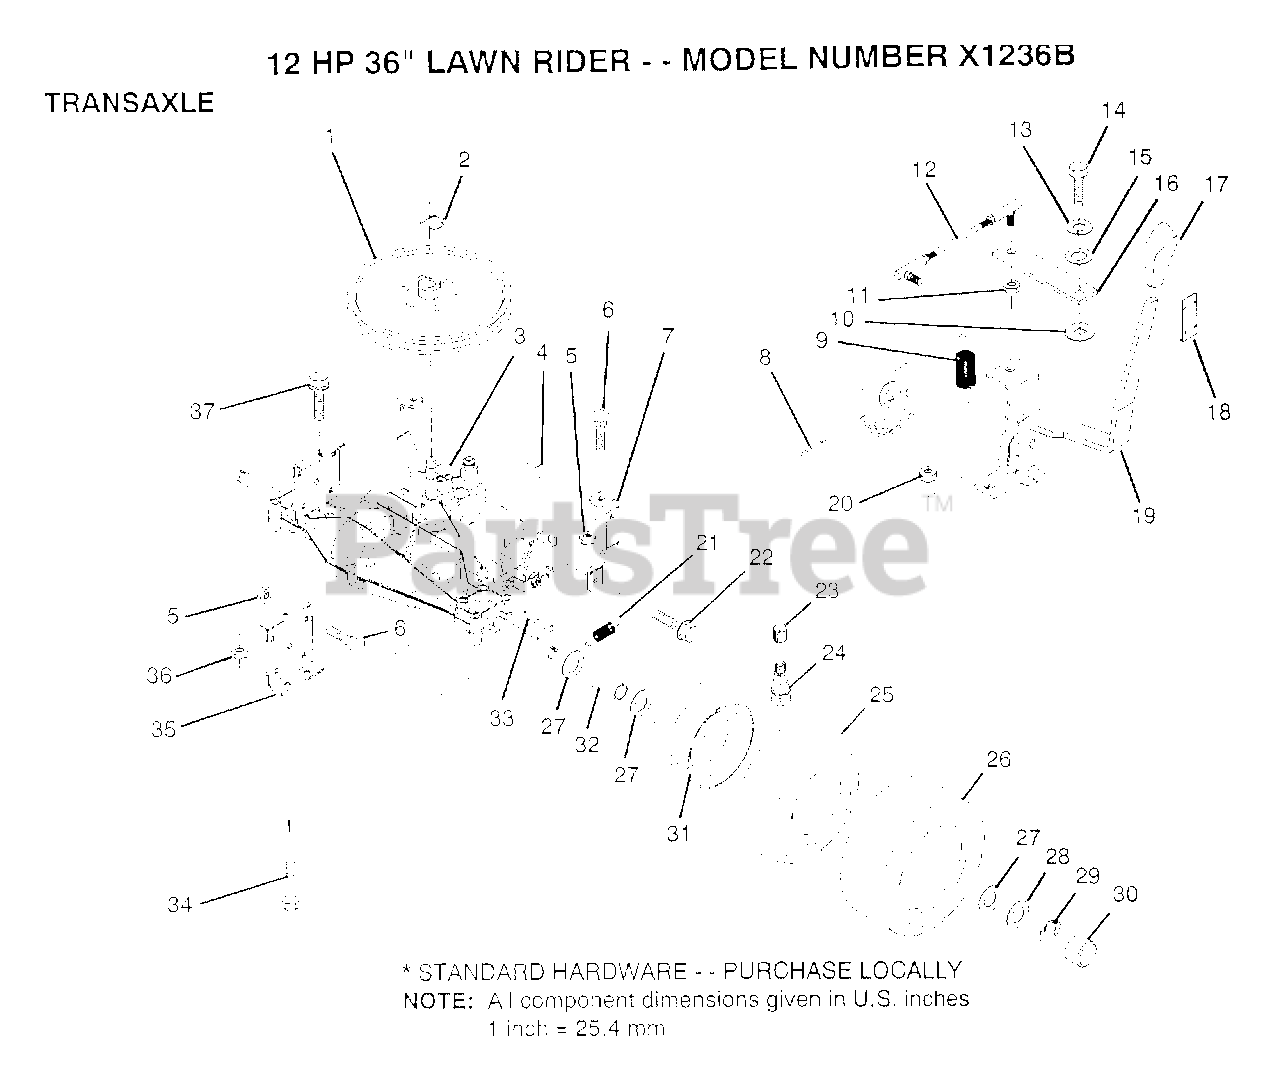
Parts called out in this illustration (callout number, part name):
1	PULLEY
6	BOLT
7	"STRAP,TORQUE"
8	PIN COTTER 1/8
9	"SPRING,EXT"
10	WASH-SHFT PLT LT
11	NUT.LOCK.5/16-24
12	"LINK,SHIFT"
13	LOCKWASHER
15	WASHER LT
16	ARM SHIFT
17	"KNOB,SHT CONTROL"
18	KNOB RETAINER
22	SCREW
23	VALVE CAP
24	VALVE STEM LT
25	TUBE.16X6.5/7.5-8
26	TIRE.16X7.5-8
27	WASHER
28	WASHER
29	E-RING LT
30	HUB CAP
32	SPACER
33	SQUARE KEY
34	BOLT
35	"BRKT,TRANSAXLE"
37	SCREW
